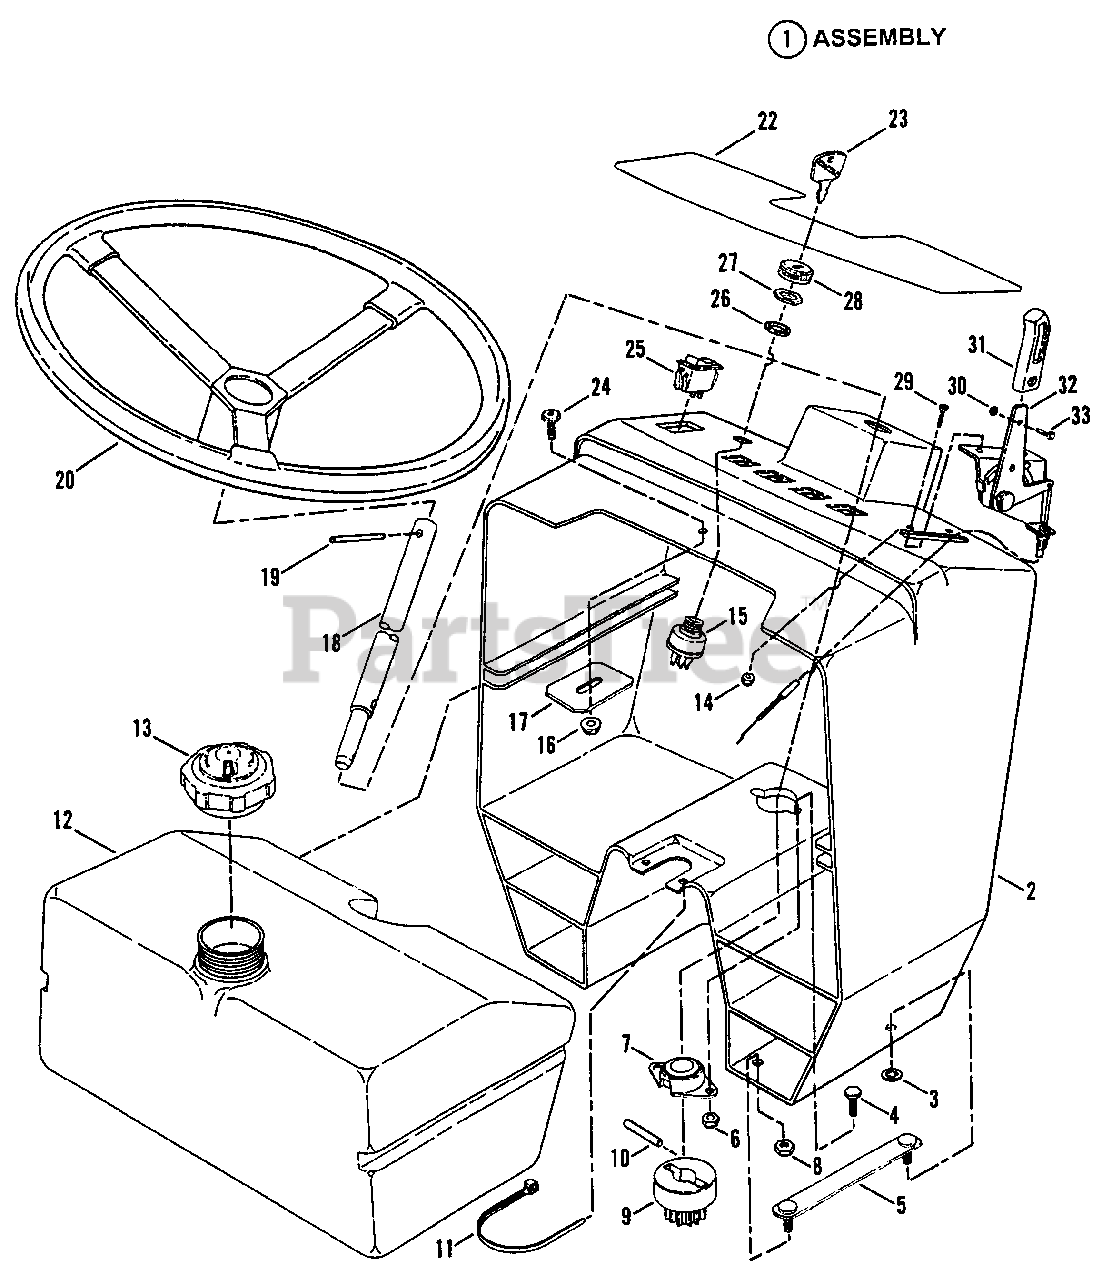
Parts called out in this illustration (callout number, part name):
1	ASSEMBLY, Console
2	CONSOLE
3	RETAINER
4	SCREW, 1/4-20 x 3/4" Hex Head Cap, Grade 5
5	ASSEMBLY, Strap-Clinch Stud
6	NUT, 1/4-20 Hex Nyloc
7	ASSEMBLY, Flange Bearing
8	NUT, 5/16-18 Hex Center Lock
9	GEAR, Pinion, Steering Shaft
10	PIN, Dowel, 1/4 x 1 1/4"
11	TIE, Wire
12	ASSEMBLY, Fuel Tank
13	CAP, Fuel Tank
14	NUT, #10-24 Hex Nyloc
15	KEYSWITCH
16	NUT, 5/16-18 Hex Flange Lock
17	BRACKET, Hood Latch Catch
18	SHAFT, Steering
19	ROLL-PIN
20	STEERING WHEEL
22	DECAL, Console
23	KEY, Switch (With Cover)
24	SCREW, 5/16-18 x 5/8" Truss Head, Torx
25	SWITCH, Lights
27	NUT, 5/8-32 Hex
28	BEZEL
29	SCREW, #10-24 x 5/8" Machine
30	NUT, #8-32 Hex
31	HANDLE, Throttle Control
32	CONTROL, Throttle
33	SCREW, #8-32 x 3/8" Cross-Recessed, Fillester Head
